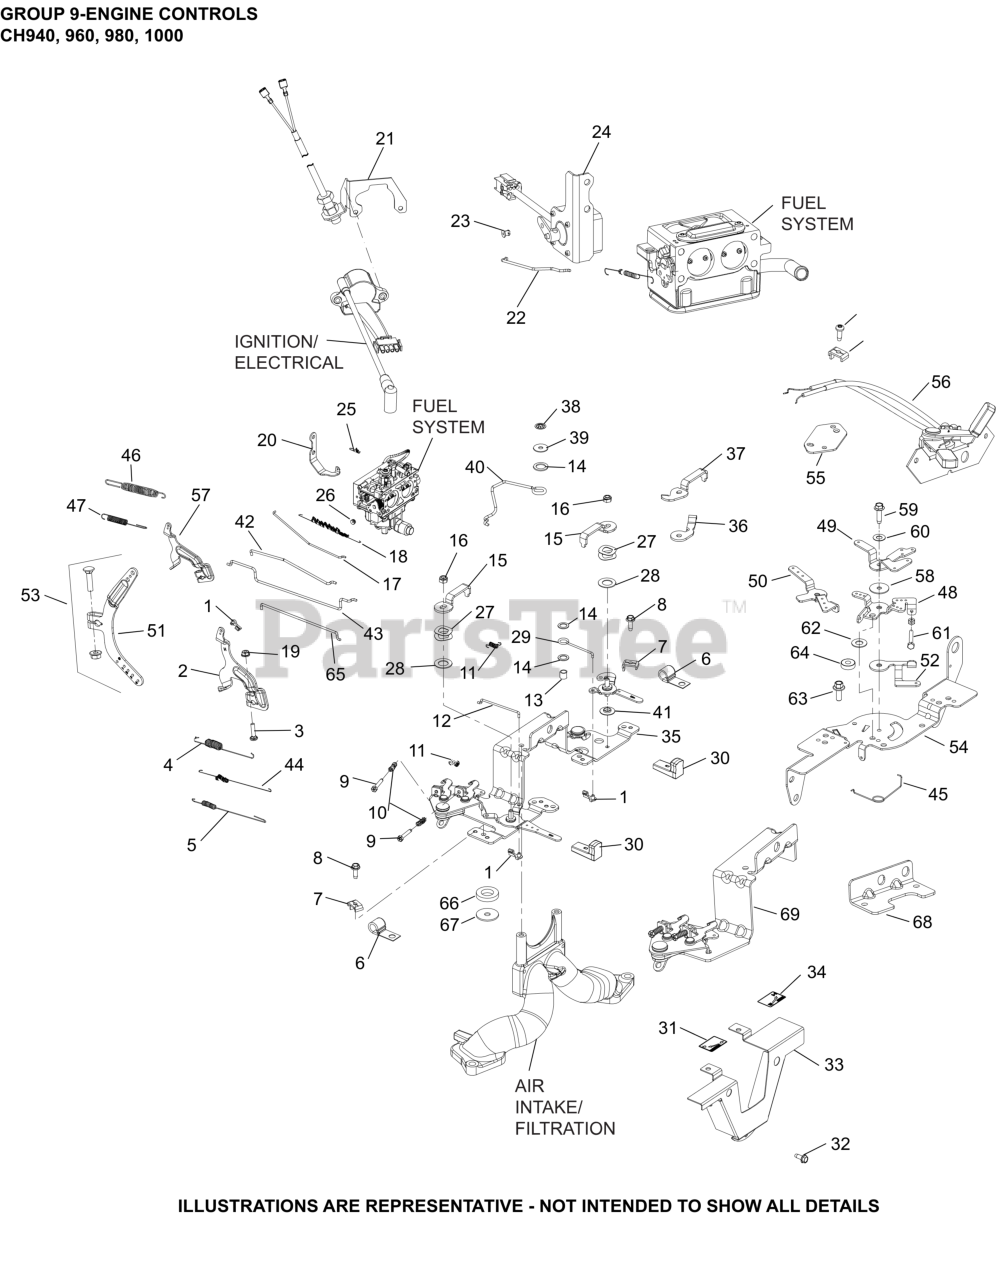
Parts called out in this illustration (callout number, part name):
1	BUSHING, THROTTLE LINKAGE
3	BOLT, RD HD SQ NECK M6X1.0X25
4	SPRING, GOVERNOR IDLE
8	SCREW, THREAD FORMING
9	SCREW, PHL THD FRM M4X0.7X25
11	SPRING, RETURN
12	LINKAGE, THROTTLE LEVER
13	BUSHING - (#DSC)
14	WASHER, NYLON
16	NUT, LOCK M6X1.0
19	NUT, FLG M6X1.0
20	BRACKET, CHOKE ASSIST
23	BUSHING, LINKAGE RETAINING
25	SPRING, CHOKE ASSIST
27	WASHER, SPRING
29	LINKAGE, CONTROL
30	KNOB, CONTROL LEVER
32	SCREW, THREAD FORMING
33	PANEL, CONTROL
34	DECAL, CHOKE
35	CONTROL ASSEMBLY, SPEED (HORIZONTAL)
36	BRACKET, MANUAL CHOKE CONTROL
38	RETAINER, PALNUT
39	WASHER, STEEL
40	LINKAGE, CHOKE HORIZONTAL
41	WASHER, NYLON SHOULDER
44	SPRING, LINKAGE
57	KIT, GOVERNOR LEVER
62	WASHER, FLAT 9 MM
65	LINKAGE, THROTTLE
66	KIT, WASHER
67	WASHER, FLAT 1/4" (O.D. 1")
NI	SPRING, GOVERNOR
